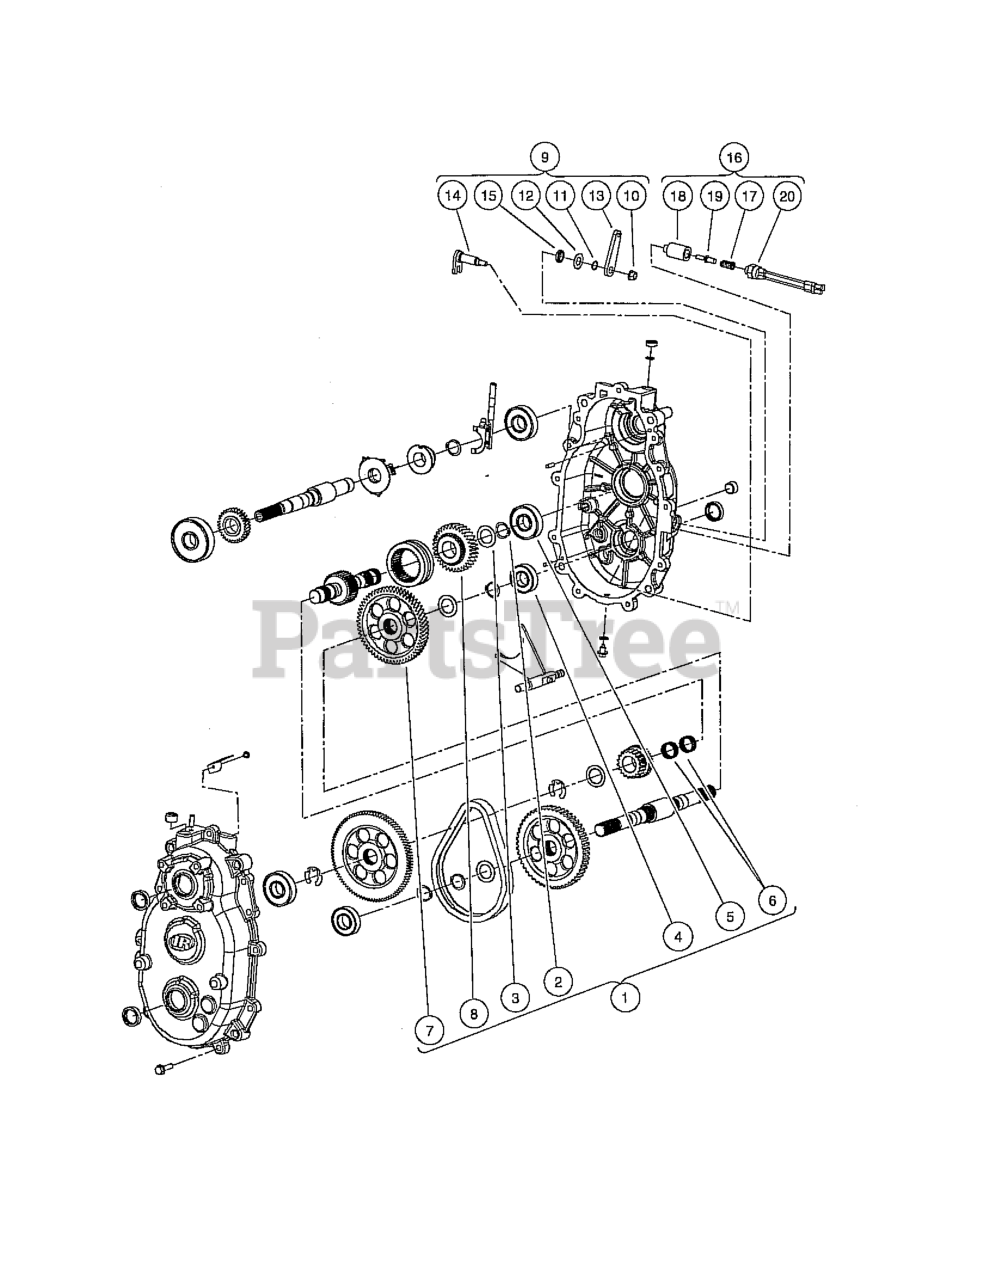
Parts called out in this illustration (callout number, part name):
1	KIT-FORWARD GEAR REPAIR
2	RING, RETAINING, BASIC EXTERNA
3	WASHER, THRUST, 1.007 X .062
4	BEARING, BALL, 6205 C3
5	BEARING, BALL, 6305 C3
6	BEARING, NEEDLE, SPLIT CAGE
9	KIT- TRANS SHIFT SHAFT REAPAIR
10	NUT, LOCK HEX, NYLON, 5/16-24
11	RING, RETAINING, EXTERNAL 9/16
12	WASHER, FLAT, .58 X 1.08 X .05
15	SEAL, DUL LIP, .88 X .56 X .19
16	KIT-NEUTRAL SWITCH REPAIR
